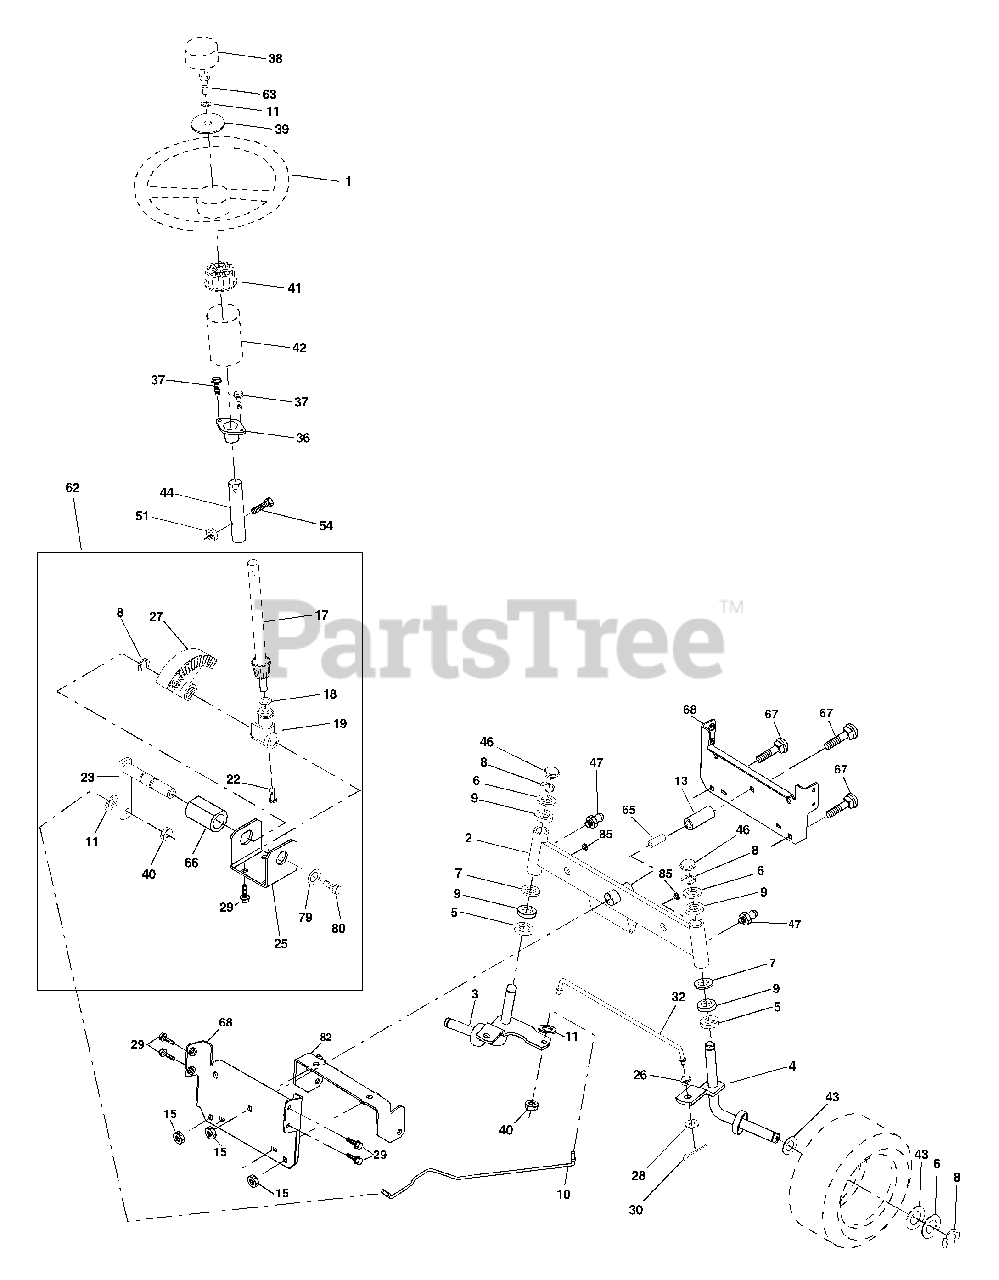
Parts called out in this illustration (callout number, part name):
1	Wheel Steering Auto Black
2	Axle Asm Front
3	Spindle Asm Lh
4	Spindle Asm Rh
5	Bearing Race Thrust Harden
6	Washer 25/32 X 1 5/8 X 16ga
7	Washer 27/32 X 1 1/4 X 16 Ga
8	Ring Klip #t5304-75
9	Bearing Col Strg Blk
10	Link Drag Extended
11	Lockwasher
13	Spacer Bearing Axle Front
15	Hex Flange Lock
17	Shaft Asm Strg 5/8 X 15 19 Lt
18	Washer Thrust 515x 750x 033
19	Support Shaft
22	Screw Hex Wsh Hd Torx
23	Shaft Asm Pittman
25	Bracket Steering
26	Bushing Rod Tie Blk Lt
27	Gear Sector
28	Washer 13/32 X 7/8 X 16ga
29	Screw 3/8-16x3/4
30	Pin
32	Rod Tie Wire Form 19 75 Mech
36	Bushing Strg 5/8 Id Dash
37	Screw TT #10-32 x 5 x 3/8 Flange
38	Insert Cap Strg
39	Washer 13/32 x 2-3/8 x 12 Ga
40	Locknut Center
41	Adaptor Wheel Strg 640/ 635id
42	Boot Dash Steering
43	Washer 25/32 X 1 1/4 X 16 Ga
44	Extension Steering Non-Adjust
46	Cap Spindle Fr Top Blk
47	Fitting Grease
51	Nut Lock Hex W/Ins.
54	Bolt Fin Hex 5/16-18 Unc P
62	Kit Steering Assembly Service
63	Bolt Fin Hex 3/8-16unc x Gr. 5
65	Spacer Brace Axle
66	Bearing Arm Pittman
67	Bolt Rdhd Sq 3/8-16 Unc x 2-3/4
68	Brace Axle
79	Washer 13/32 x 1-1/4 x 12 Ga
80	Bolt Hex Nylon 3/8-16 x 3/4
82	Bracket Susp Chassis Front
85	Fastner Christmas Tree
